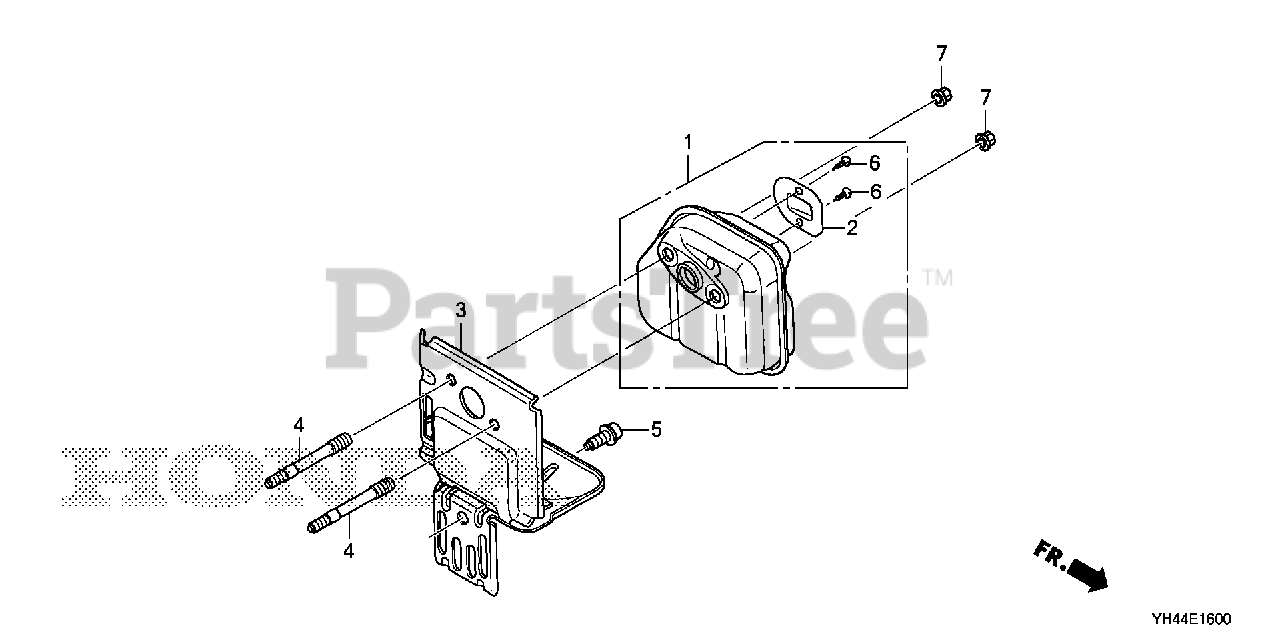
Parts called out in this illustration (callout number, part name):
1	MUFFLER
2	ARRESTER, SPARK
3	GUIDE, AIR EX.
4	BOLT, STUD (5X52)
5	BOLT, SOCKET (5X10)
6	SCREW, TAPPING (4X6) (TO INSTALL OPTIONAL SPARK ARRESTER)
7	NUT, SELF-LOCK (5MM)
